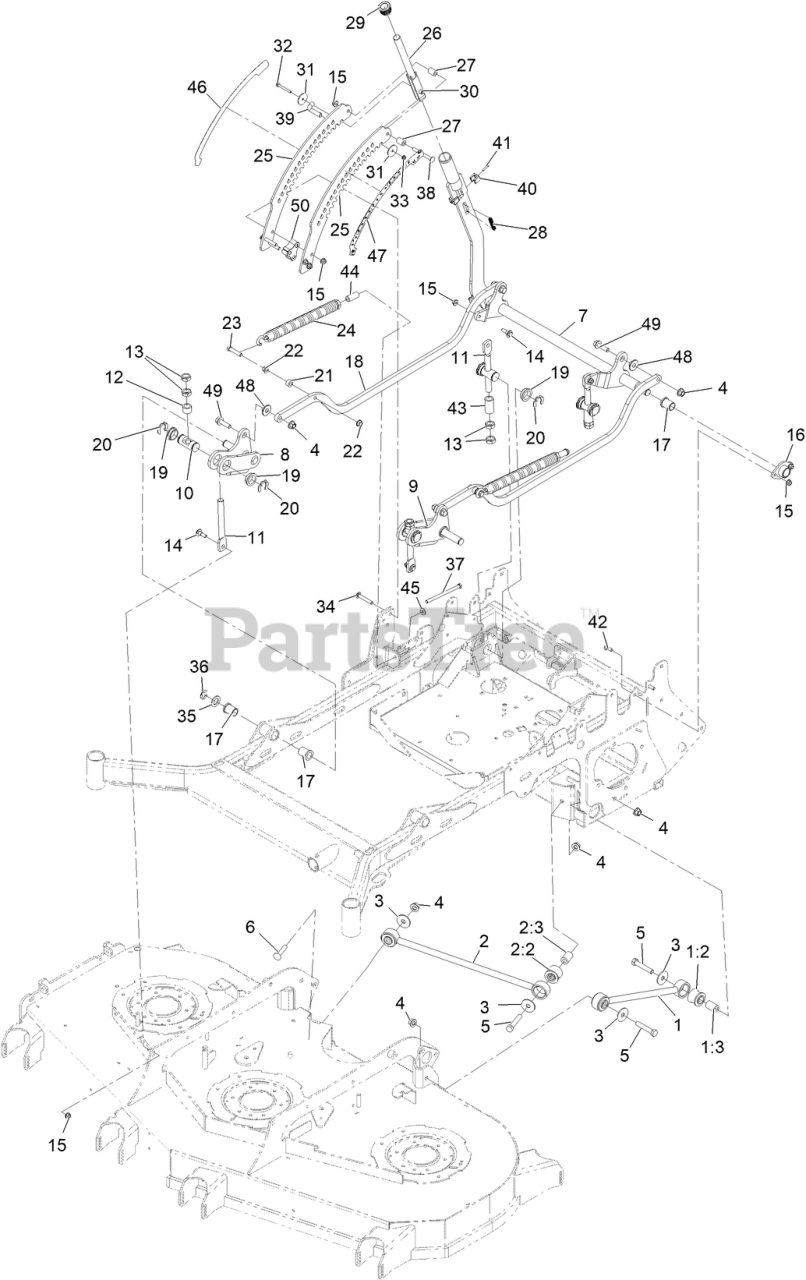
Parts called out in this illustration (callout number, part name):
1	ASM, DECK STRUT
1:2	BUSHING-RUBBER
2	PANHARD ROD ASM
2:2	BUSHING-SUSPENSION, RUBBER
3	WASHER-THRUST
4	Nut-Lock 1/2-13
5	SCREW-HH
6	SCREW-CARR
7	CROSS SHAFT -DECKLIFT-REAR
8	WELD-ARM-DECKLIFT-FRONT-RH
9	WELD-ARM-DECKLIFT-FRONT-LH
10	TRUNION-DECKLIFT GROOVED
11	Link,Deck Lift Adjuster
12	SPACER-DECKLIFT
13	NUT-JAM
14	SCREW-SHOULDER, HHF
15	NUT-HF, NI
16	Support-HOC Shaft
17	BUSHING-FLANGED
18	LINK-HOC 72
19	BUSHING-FLANGED HOC
20	E-RING WIDE GRIP
23	SCREW-HH
24	SPRING-EXTENSION
25	PLATE-HOC
26	ASM-PLUNGER-HOC
27	TUBE-INTERLOCK
29	PLUG-PLASTIC HOC
31	SPACER-HOC
32	SCREW-HHF
34	SCREW-CARR
36	RING-RETAINING, EXT
37	BOLT-TAP, HH
38	SCREW-CARR
39	PIN-HOC
40	CHANNEL-HOC GUIDE
41	SCREW-SHWH
42	SCREW-CARR
43	SPACER 1.13 O.D. X .81 I.D. X 2.05L
44	SPACER-HOC
46	DECAL-HEIGHT OF CUT,OUTER
47	DECAL-HEIGHT OF CUT-INNER
49	SCREW-HHF
50	SPACER-HOC VERTEX
